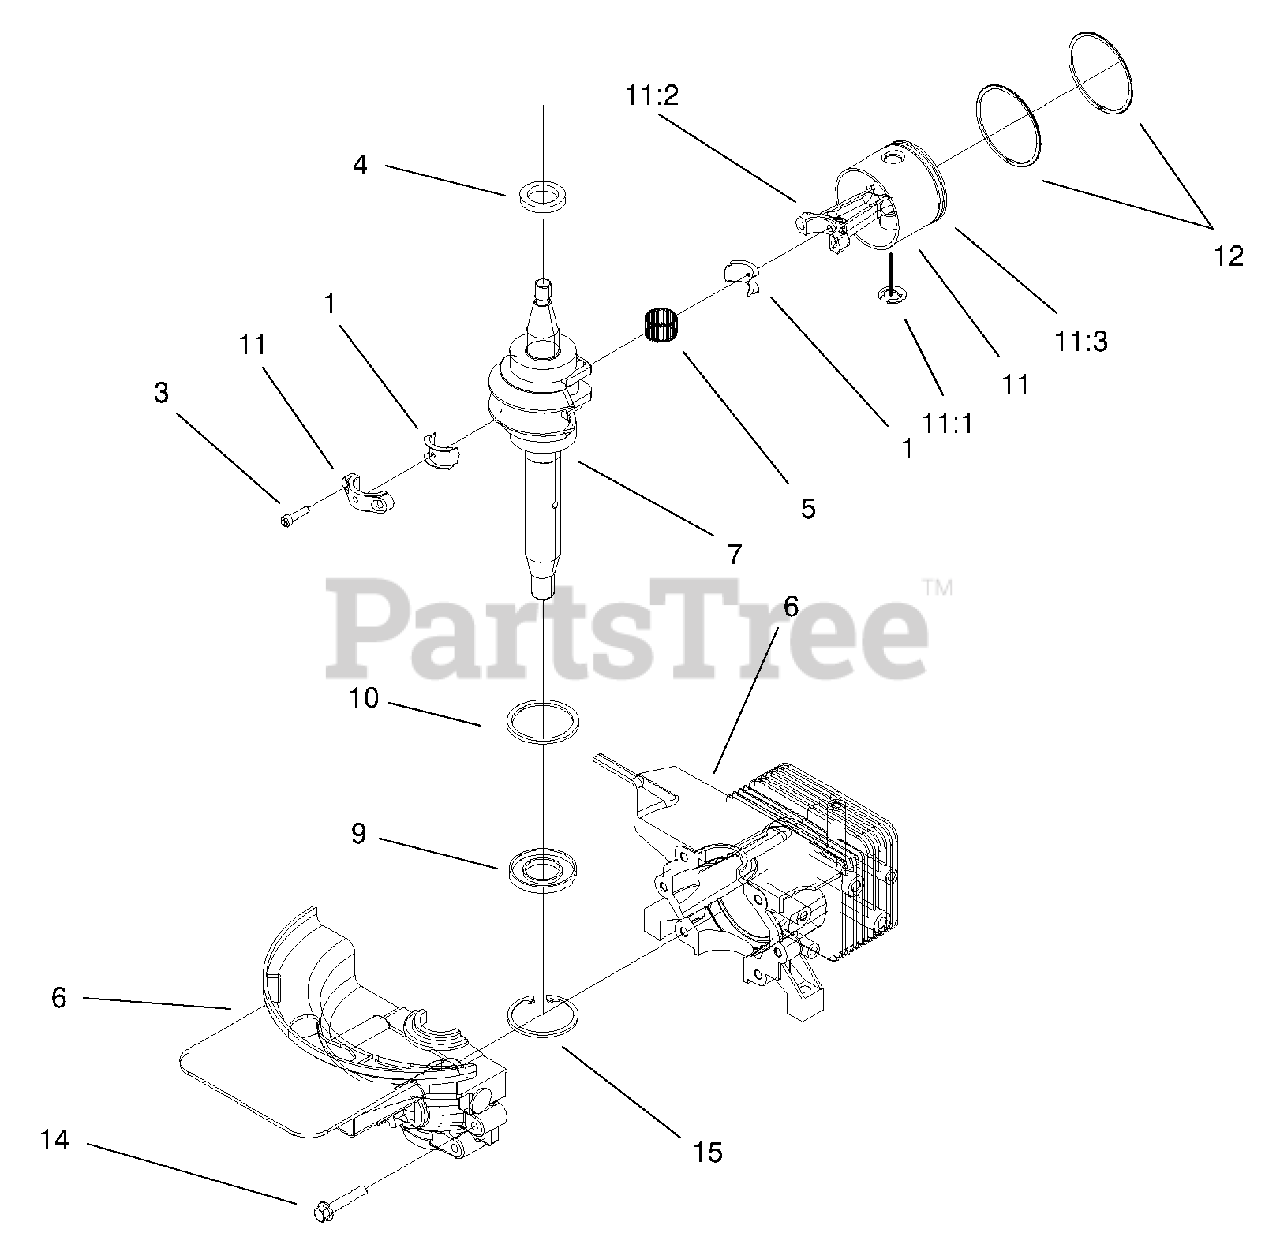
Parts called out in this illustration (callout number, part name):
1	LINER ASM
2	SEALER-LOCTITE 50CC
2	SEALER-LOCTITE 6CC
3	SCREW-HSH
4	SEAL-OIL
5	BEARING-NEEDLE
6	CYLINDER AND CRANKCASE ASM
7	CRANKSHAFT AND BEARING ASM
9	SEAL-OIL
10	RING-RET. EX
11	Piston&rod Ay
11:1	RING-RETAINING
11:2	CONNECTING ROD ASM
11:2	Piston&rod Ay
11:3	Piston & Rod ASM
11:3	PISTON AND RINGS ASM
12	Ring Set
15	RING-RETAINING
